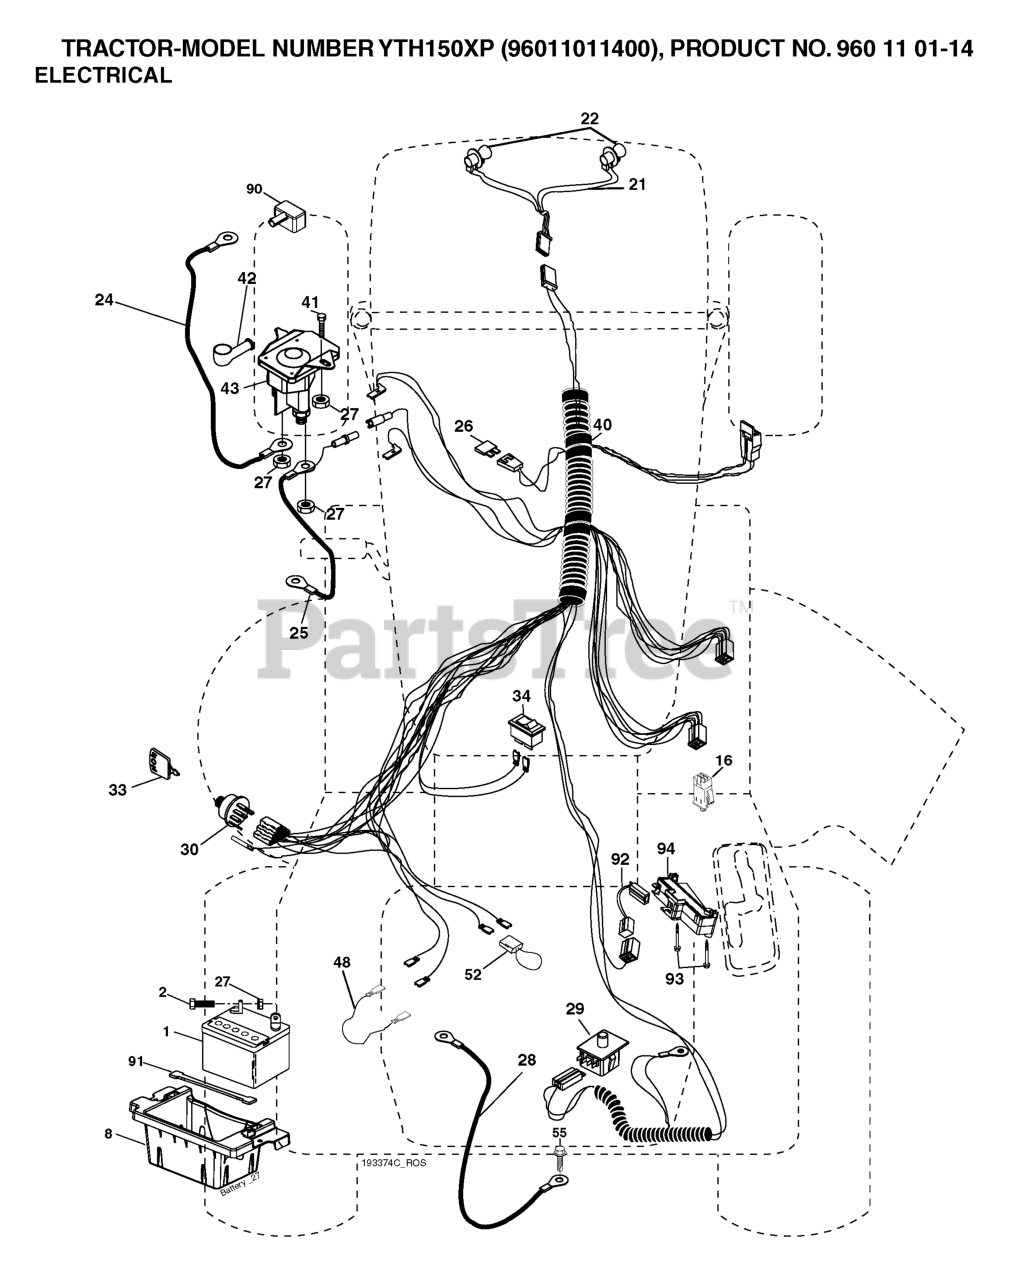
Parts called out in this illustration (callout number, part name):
1	BATTERY 12V .35 AMP
2	BOLT.HEX.1/4.X.3/4.DICHROMATE
8	BOX.BATTERY.MOUNT.FRONT.LT
16	SWITCH INTERLOOK PUSH-IN
21	HARNESS.W/LIGHT SOCKET
24	BATTERY CABLE GT
25	CABLE BATTERY 6 GA 22" W/16W
26	FUSE 20AMP
27	NUT
28	CABLE GROUND 6 GA 21" 90T BLK
29	SWITCH.SEAT.DP W/RAMPS
30	SWITCH.IGN.DELTA.W.LGH.ROS
33	KEY MLD GEN DELTA
40	Harness Ign
41	BOLT
42	TERMINAL COVER
43	SOLENOID.W/BRASS.PLUNGER
48	ADAPTER.AMMETER
52	WIRE PROTECTION LOOP
55	Screw 5/16-18 x 1/2 Hex, Self Tapping 5/16-18 x 1/2
80	HARNESS, CLUTCH
91	STRAP.BATTERY.MOUNT.FRONT(2 2)
92	HARNESS.PIGTAIL.REVERSE.SWITCH
93	SCREW.PLASTITE
94	MODULE.REVERSE.ROS
